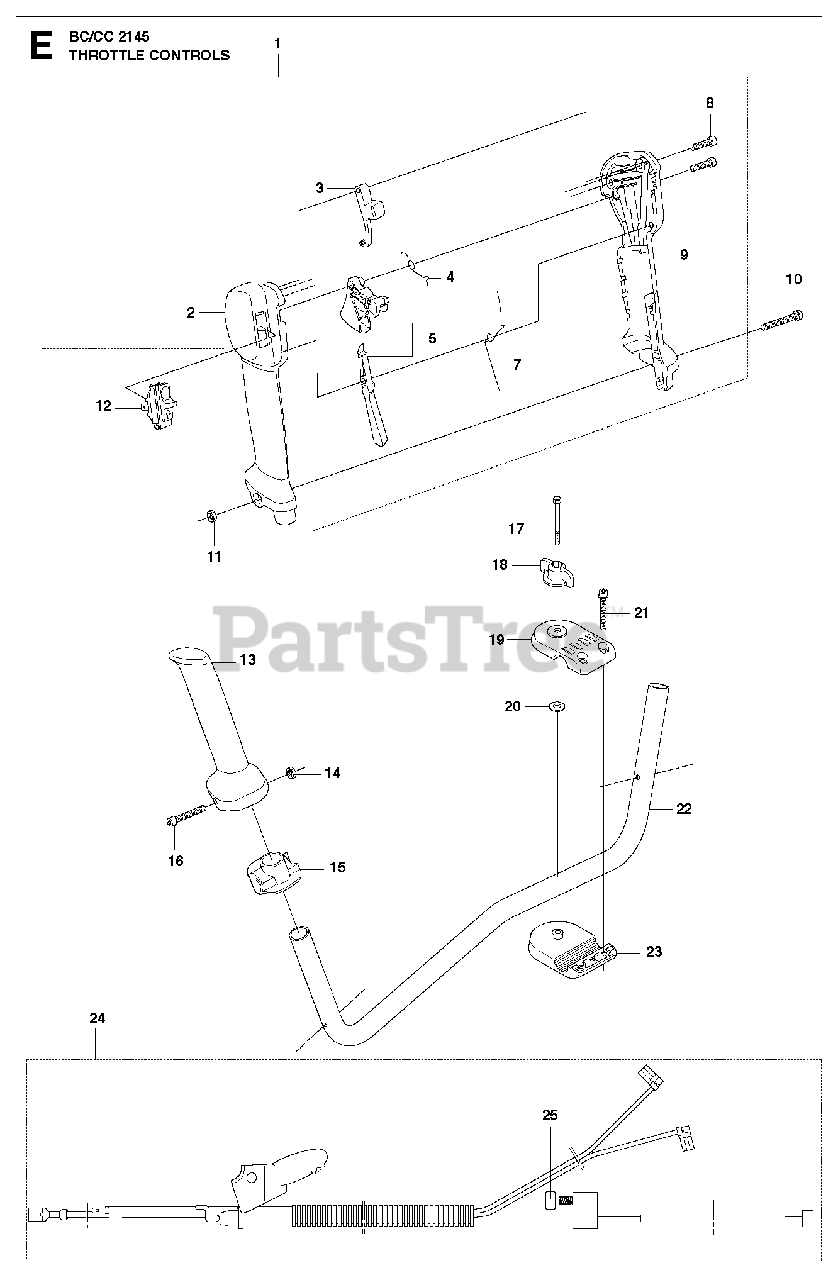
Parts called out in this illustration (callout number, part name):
1	THROTTLE HANDLE ASSY
3	SWITCH
4	SPRING
5	THROTTLE CONTROL
7	SPRING
8	SCREW
9	HANDLE HALF RIGHT
10	%SCREW
12	STOP BUTTON
14	NUT M6M M5
15	HANDLE FASTENER
17	%SCREW
19	HANDLE BRACKET
23	HANDLE BRACKET
24	WIRING ASSY
25	SCREW
